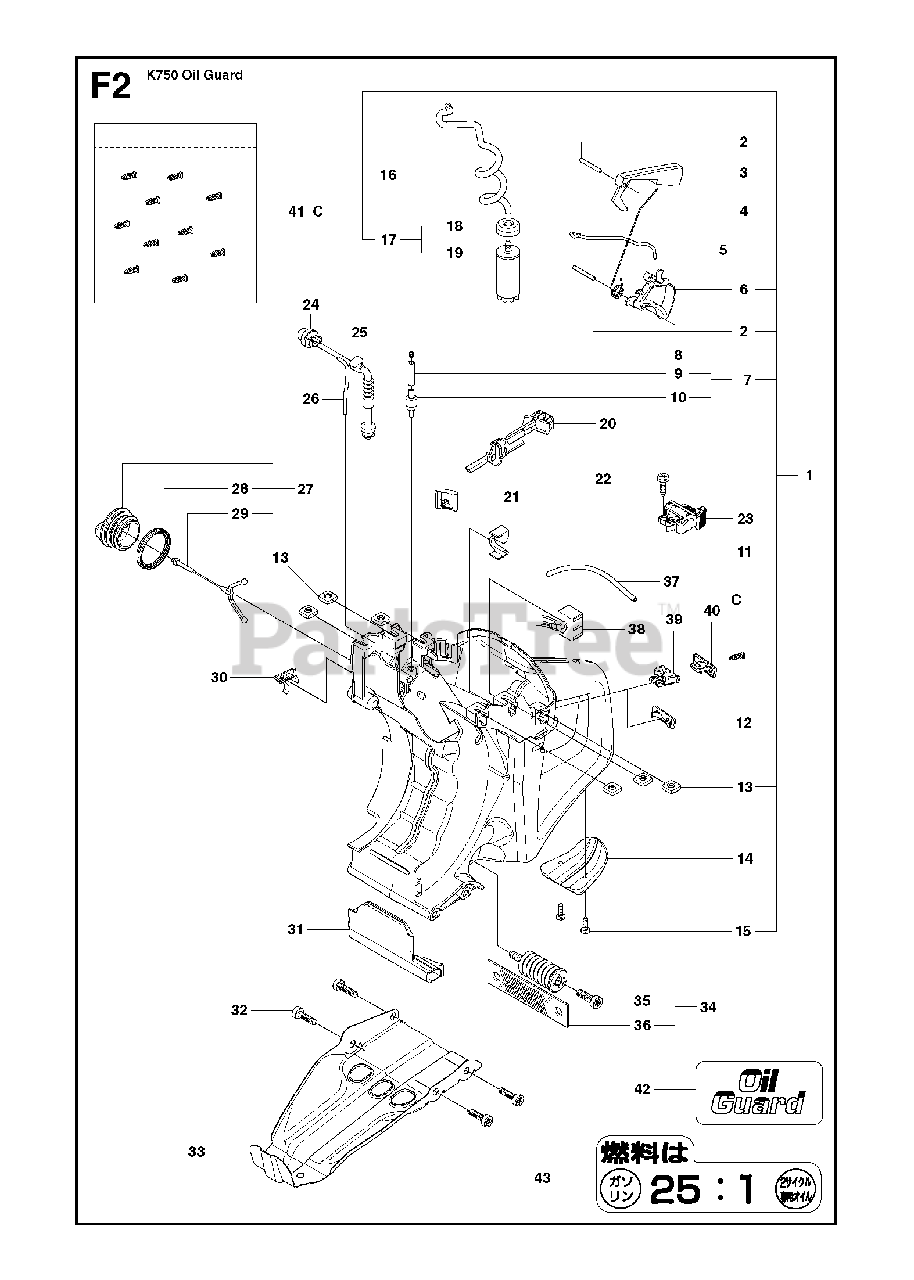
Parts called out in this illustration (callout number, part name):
1	FUEL TANKIncl. 2 - 4, 3 - 7, 11 - 17, Purge
1	FUEL TANKIncl. 2 - 4, 3 - 7, 11 - 17
2	PARALLEL PIN
3	THROTTLE LOCKOUT
3	THROTTLE LOCKOUTBlue Oilguard
4	SPRING
5	THROTTLE ROD
6	THROTTLE TRIGGER
6	THROTTLE TRIGGERBlue Oilguard
7	TANK VENT ASSYIncl. 8 - 10
14	GROUND SUPPORT
15	SCREW CRCSFT
16	FUEL HOSE
17	FUEL FILTERIncl. 18 - 19
20	CHOKE CONTROL
22	SCREW CCRPANT
23	STOP SWITCH
25	FUEL HOSEPurge
26	FUEL HOSEPurge
27	TANK CAP ASSYIncl. 28 - 29
32	SCREW ITXSCT
34	ANTIVIBRATION ELEMENTIncl. 35 - 36
35	SCREW ITXSCM
37	FUEL HOSEOil Guard
38	ELECTRONIC BOXOil Guard
39	HOUSINGOil Guard
40	SWITCHOil Guard
41	KITOil Guard, Incl. 10 pins
42	LABELOil Guard
43	LABELJapan only
